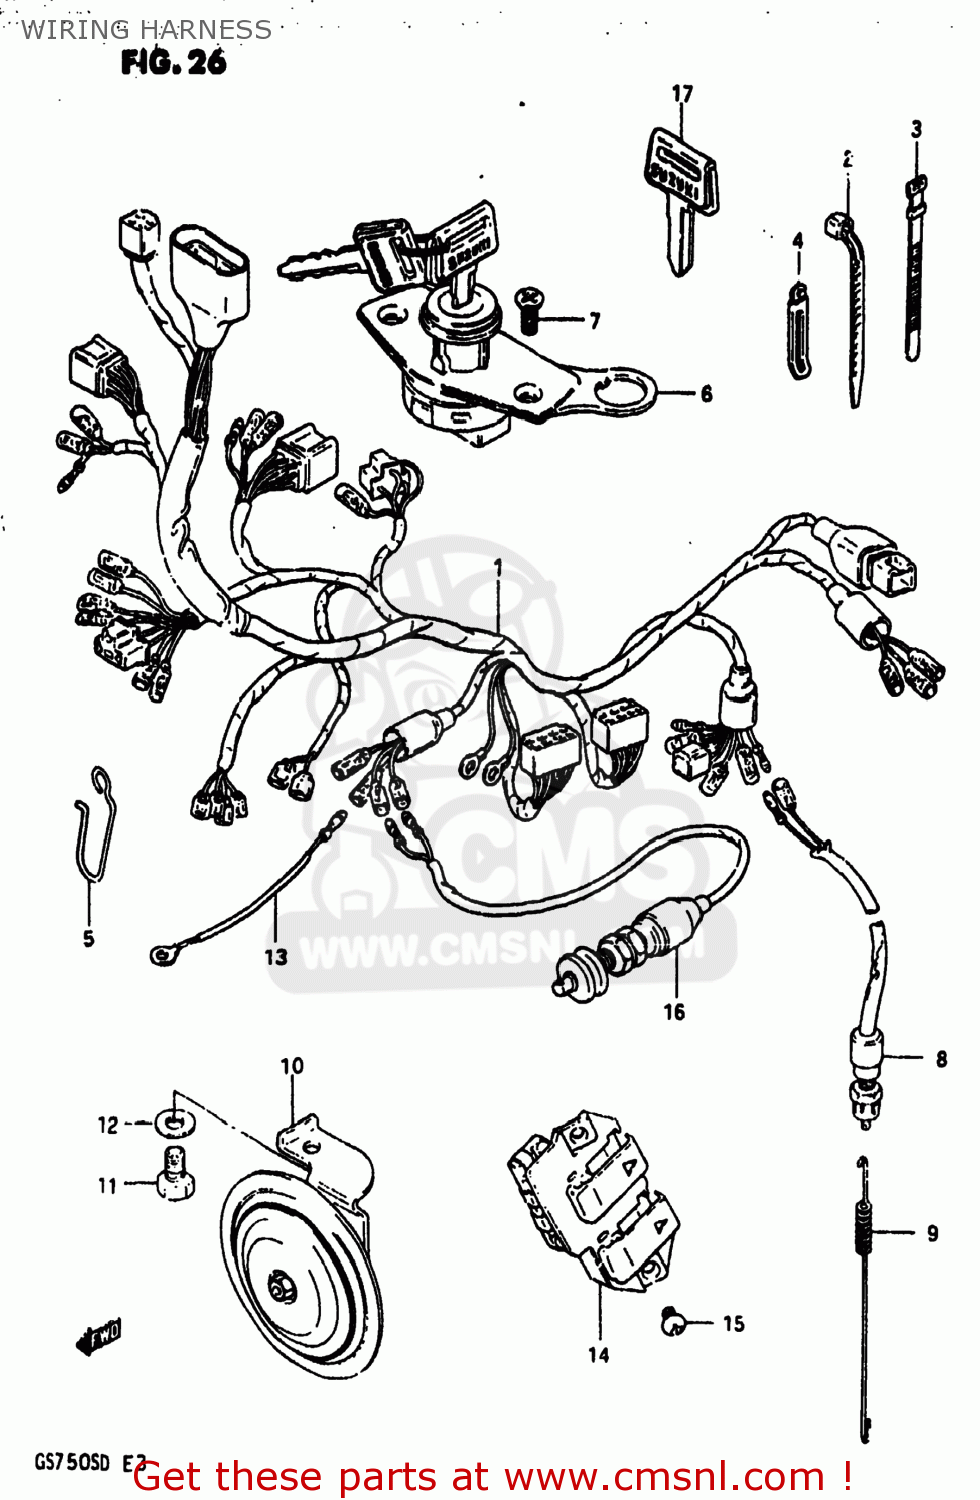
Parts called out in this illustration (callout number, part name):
1	HARNESS,WIRING
2	CLAMP(L:95)
3	CLAMP(L:80)
4	CLAMP
5	BOOT,WIRING HARNESS
6	SWITCH ASSEMBLY,IGNITION
7	SCREW
8	SWITCH ASSEMBLY,STOP LAMP
9	SPRING
10	HORN ASSY
11	BOLT 8X12
12	WASHER
13	WIRE
14	SWITCH ASSY,SIDE COVER,L
15	SCREW
16	SWITCH ASSEMBLY,SIDE STAND
17	KEY,BLANK
